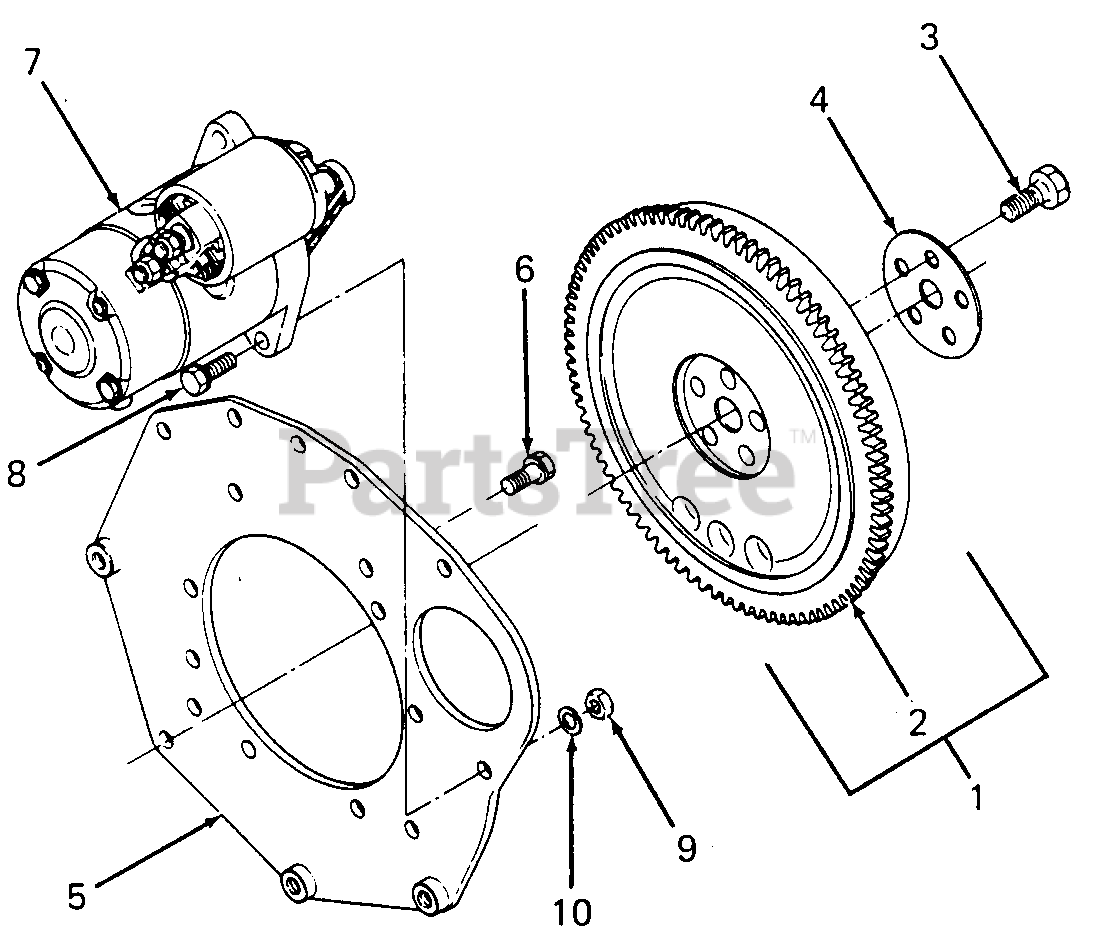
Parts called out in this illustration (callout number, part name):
1	Flywheel Assy
3	Bolt, Flywheel
4	Washer, Flywheel
5	Plate, Rear End
6	Screw, Hex Cap w/Washer
7	Starter
8	Screw, Hex Cap w/Washer
10	Washer, Lock
